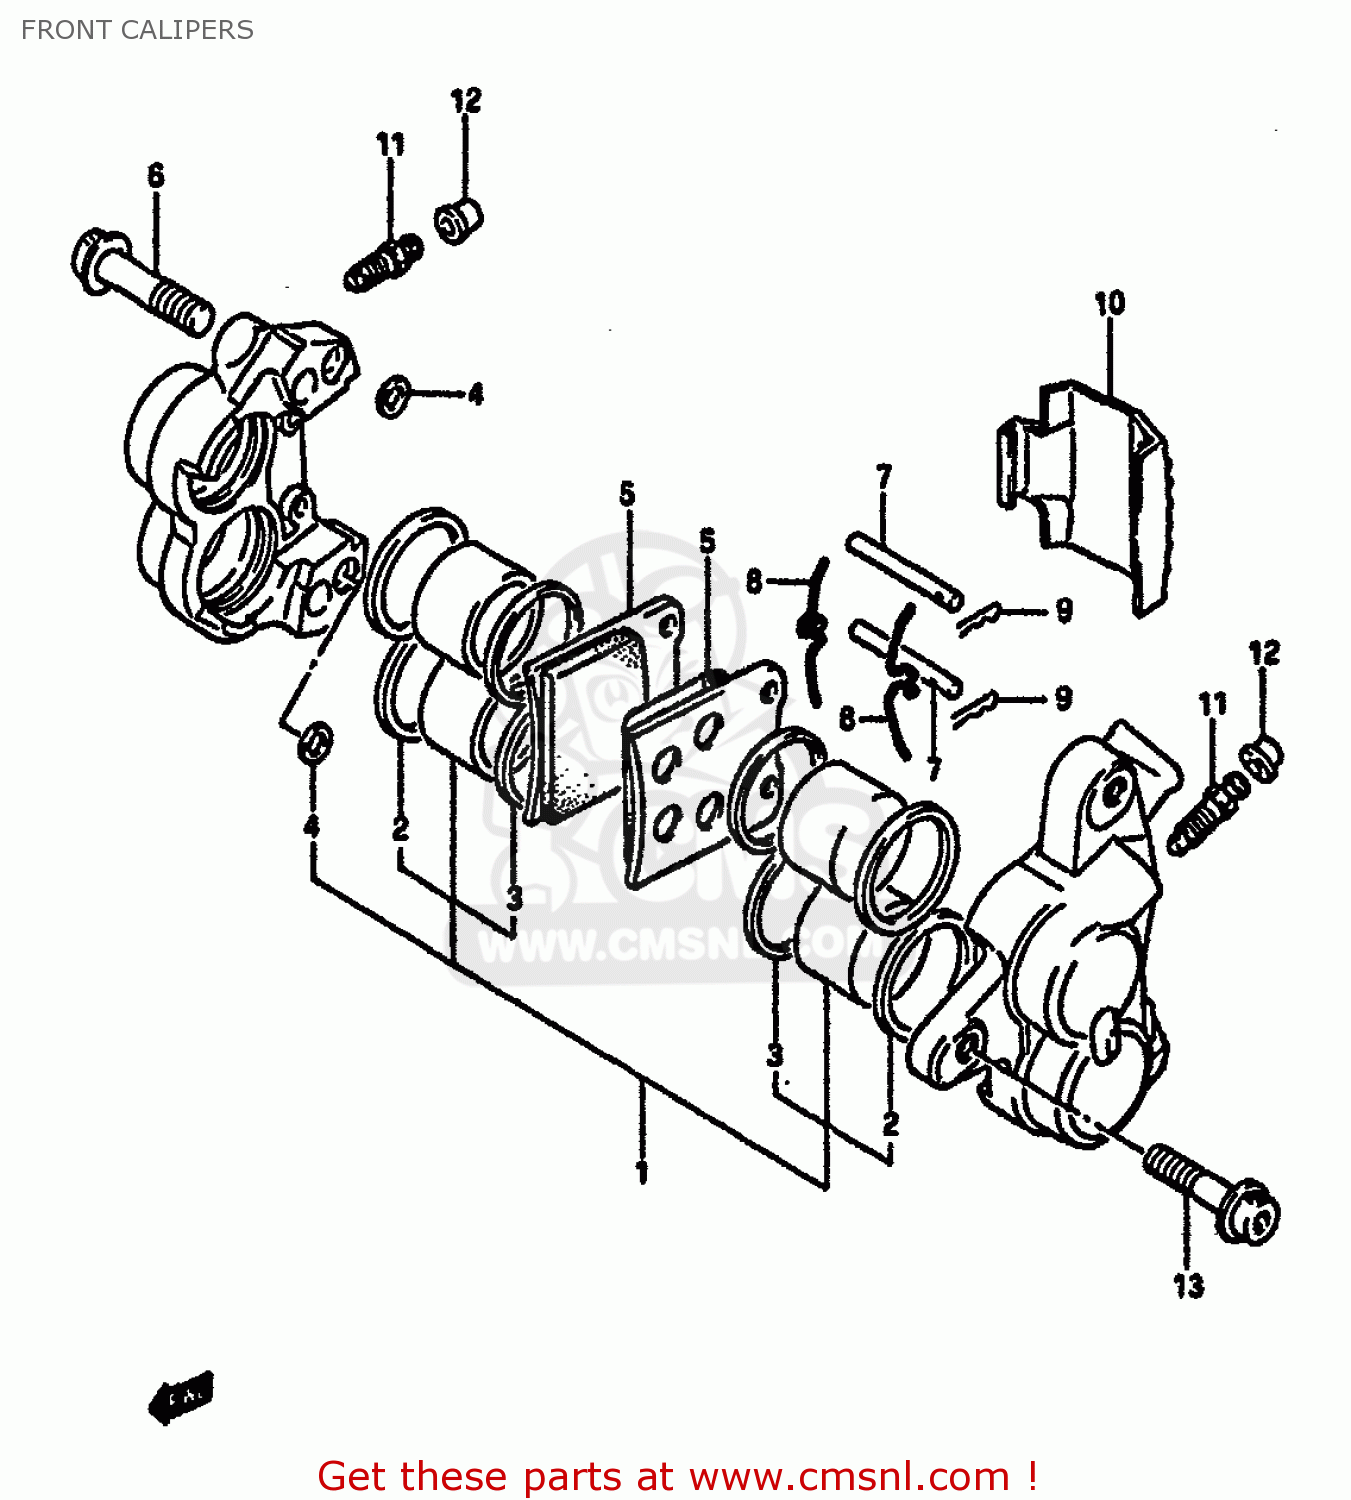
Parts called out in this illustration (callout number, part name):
1	PISTON SET
2	SEAL,PISTON
3	SEAL,WIPER
4	SEAL,JOINT
5	PAD,BRAKE (MCA)
6	BOLT,HOUSING
7	PIN,PAD
8	SPRING
9	CLIP,PAD PIN
10	COVER,CALIPER
11	BLEEDER
12	CAP,BREATHER
13	BOLT
